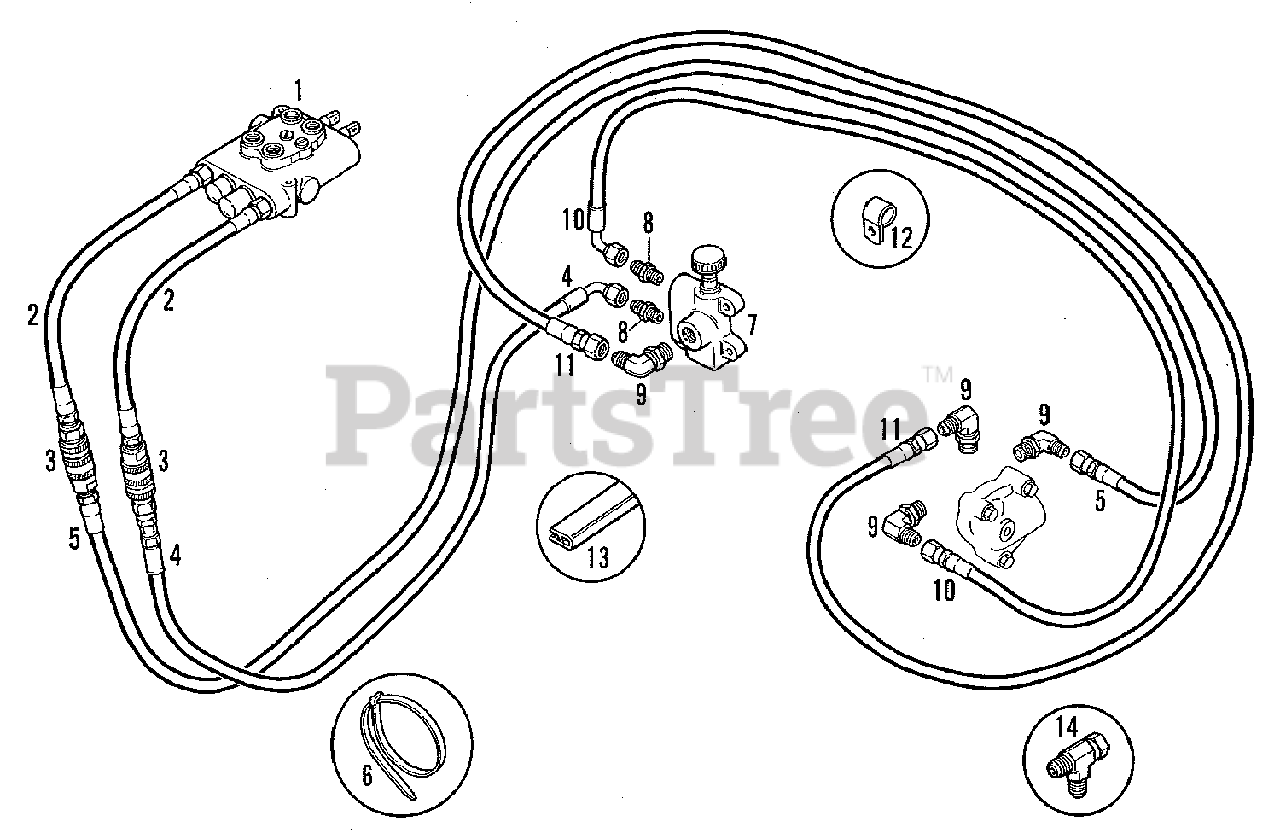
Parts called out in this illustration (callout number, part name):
1	VALVE ASSEMBLY, Complete
1	CAPSCREW, 1/4NC x 2
1	LOCKWASHER, 1/4
2	HOSE ASSEMBLY, Valve (Inlet & Outlet)
3	COUPLER, Hose
4	HOSE ASSEMBLY, Pressure
5	HOSE ASSEMBLY, Return
6	TIE, Plastic
7	VALVE ASSEMBLY, Selector
7	CAPSCREW, 5/16NC x 2
7	NUT, 5/16NC
8	CONNECTOR, Straight, 3/8 Tube O.D.
8	O-RING, 15/32" I.D.
9	ELBOW, 90 Degrees x 3/8
10	HOSE ASSEMBLY (Top Port of the Selector Valve to the Diverter Block Inlet)
11	HOSE ASSEMBLY (From Diverter Block to Selector Valve
12	CLAMP, Hose
12	CAPSCREW, 5/16NC x 1
12	LOCKWASHER, 5/16
12	NUT, 5/16NC
13	STRIP, (Attached to Rear of R.H. Panel Cutout Under Seat to Protect Hoses)
14	TEE, Swivel, 3/8 tube O.D.
